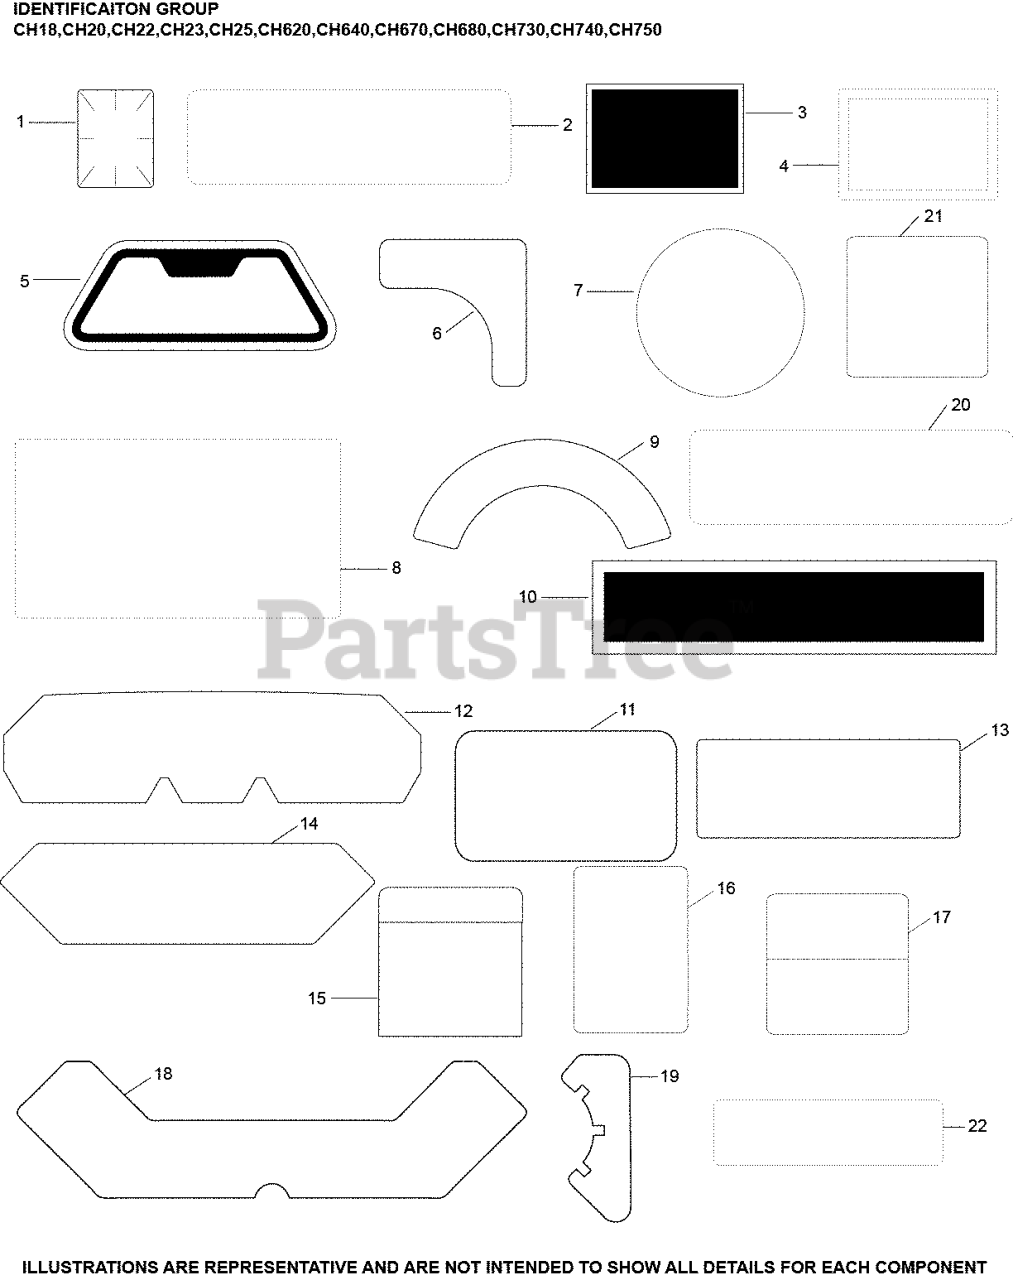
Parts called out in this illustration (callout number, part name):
1	LABEL, CLEAR LAMINATION - USE 25 113 79-S
5	DECAL, OIL SENTRY - (#DSC)
9	DECAL, ENGINE MAINTENANCE-DISC.
9	DECAL, 20 HP - DISCONTINUED
20	DECAL LPAC, 20.5 HP/674cc/CV-CH640
22	LABEL, ENGINE DISPLACEMENT (CH670 20HP)
